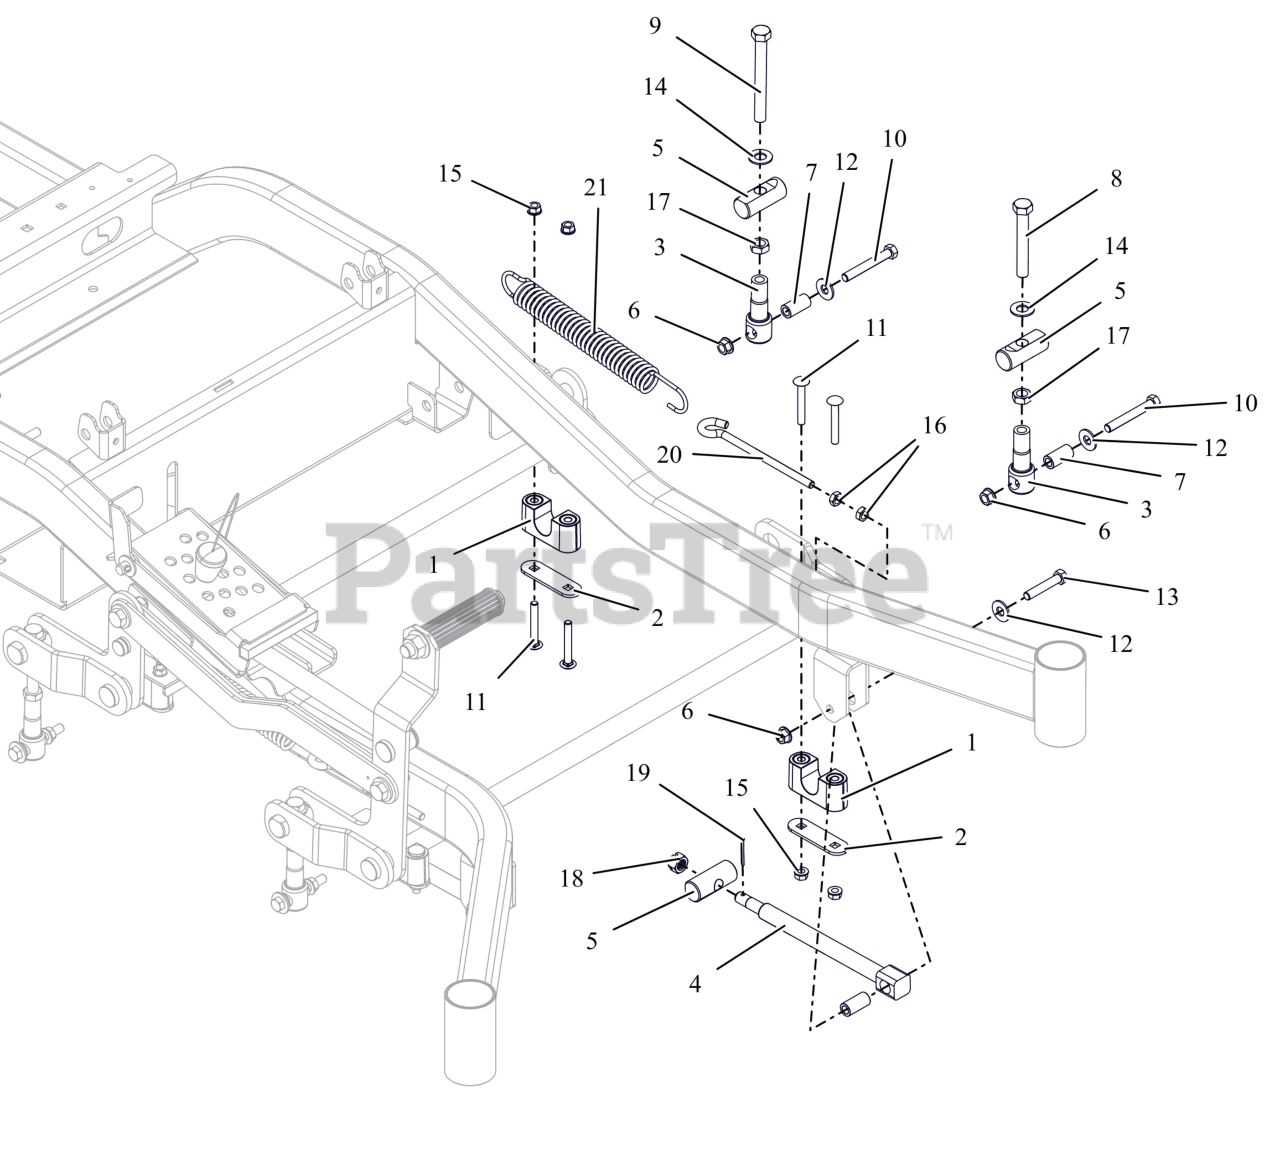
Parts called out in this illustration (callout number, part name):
1	ASM-BUSHING, DECK LIFT
2	PLATE, BEARING SUPPORT
3	LINK, DECK LIFT FORMED
4	DRAG,LINK-HD
5	PIN, DECK LIFT
6	NUT-LK-TOP-FLG .38-16 ZC120
7	SPACER, DECK LEVELING
8	BLT, HEX .50-13X3.50F G5 ZCC
9	BLT, HEX .50-13X4.50F G8 ZCC
10	BLT, HEX .38-16X2.75 G8 ZCC
11	BLT, RHSSN.31-18X2.25 G5 ZCC
12	WSHR,FLT .438X1.00X.083 ZCC
13	BLT,HEX .38-16X2.00 G5 ZCC
14	WSHR, FLT .557X1.040X.102 ZCC
15	NUT,LK-CTR-FLG .31-18 GF ZCC
16	NUT-JAM .375-16 GR2 E-COAT
17	NUT-JAM .500-13 G2 ZCC
18	NUT-SL .50-13
19	PIN,CTR.12X1.25EXTPRSQCT ZC120
20	BOLT, J-HOOK .38-16X5.25 E-COAT
21	SG-TENS .162X1.25X8.25 E-COAT
